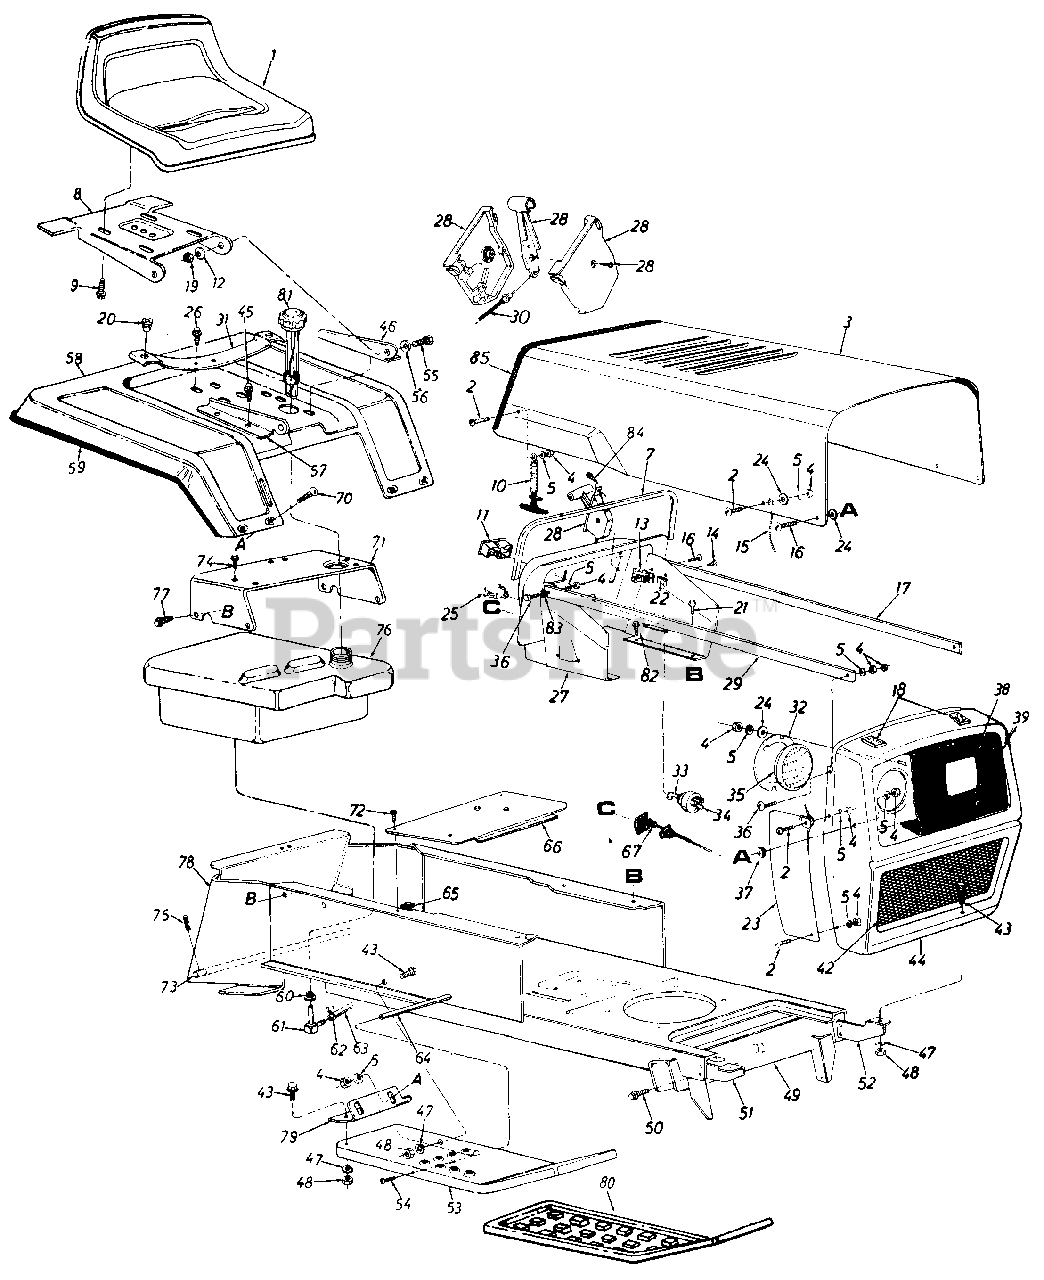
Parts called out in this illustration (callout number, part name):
1	Seat Assembly
2	Truss Mach. Scr. 1/4-20 x .50" Lg.*
5	L-Wash. 1/4" Scr.
7	Vinyl Molding Strip-29"
8	Seat Pivot Bracket
9	Hex Wash. AD AB-Tap Scr. 318 x .75" Lg .
10	Hood Latch Ass'y.
11	Ammeter
12	Bell-Wash .341" I.D. x .88" O.D.
13	Circuit Breaker 8 Amp.
14	Hex Tap Scr. #10 x .50" Lg.
15	Hood Stop
16	Truss Mach. Scr. 1/4-20 x .75" Lg.
17	Grille Positioning Rod
18	PVC Foam Strip 1/2 x 1.00" x 2.00" Lg.
19	Hex Cent. L-Nut 5/16-18 Thd.
20	Grommet
21	Hex Thd. Rolling Scr. 1/4" x .50" Lg.
22	Speed Nut #10Z
23	Grille Side Panel-R.H.
24	Fl-Wash. 1/4" I.D.
25	Light Switch
26	Hex Wash. Hd. Self-Tap Scr. 5/16-18 x .50" Lg.
27	Dash Panel Ass'y.
28	Throttle Control Box Comp.
29	Grille Positioning Rod
30	Throttle Control Wire
31	Seat Spring
32	Head Lamp Retainer
33	Ignition Key
34	Ignition Switch
35	Head Lamp
36	Truss Machine Scr. 1/4-20 x .75" Lg.
37	Rubber Wash. .50" I.D. x 1.00 O.D. x .25 Thk.
38	Headlight Bezel
39	Hex Wash. Hd. Scr. #8-32 x .38" Lg.
42	Grille Screen
43	Hex Scr. 5/16-18 x .75" Lg.
44	Grille Ass'y.
45	Hex Wash. Hd. Self-Tap Scr. 5/16-18 x .50" Lg.
46	Seat Brkt.-L.H.
47	L-Wash. 5/16" Scr.*
48	Hex Nut 5/16-18 Thd.*
49	Lower Frame Ass'y.
50	Hex Thd. Rolling AB Scr. 5/16 x .75" Lg.
51	Grille Mount Brkt.-R.H.
52	Grille Mount Brkt.-L.H.
53	Running Board-R.H.
54	Truss Mach. Scr. 5/16-18 x .75" Lg.*
55	Hex Bolt 5/16-18 x .75" Lg.*
56	Bell-Wash. .34" I.D. x .88" O.D.
57	Seat Brkt.-R.H.
60	Bushing
61	90ø Nipple
62	Hose Clamp
63	Gas Line 46" Lg.
64	Running Board Rod
65	Speed Nut
66	Transmission Cover
67	Choke Control Comp.
70	Carriage Bolt 1/4-20 x .50" Lg.*
71	Seat Mounting Channel
72	B-Tap Scr. #10 x .50" Lg.
73	Hitch Rod
74	Hex Wash. Hd. Self-Tap Scr. 5/16-18 x .50" Lg.
75	Internal Cotter Pin
76	Gas Tank
77	Hex Wash. Hd. AB-Tap Scr. 318 x .75" Lg.
78	Hitch Plate
81	Gas Gauge
82	Hex Thd. Rolling Scr. 5/16-24 x .75" Lg.
83	External Wash. 1/4" I.D.
84	Truss. Mach. Scr. #10 x .5" Lg.
85	Trim strip-30" Lg.
